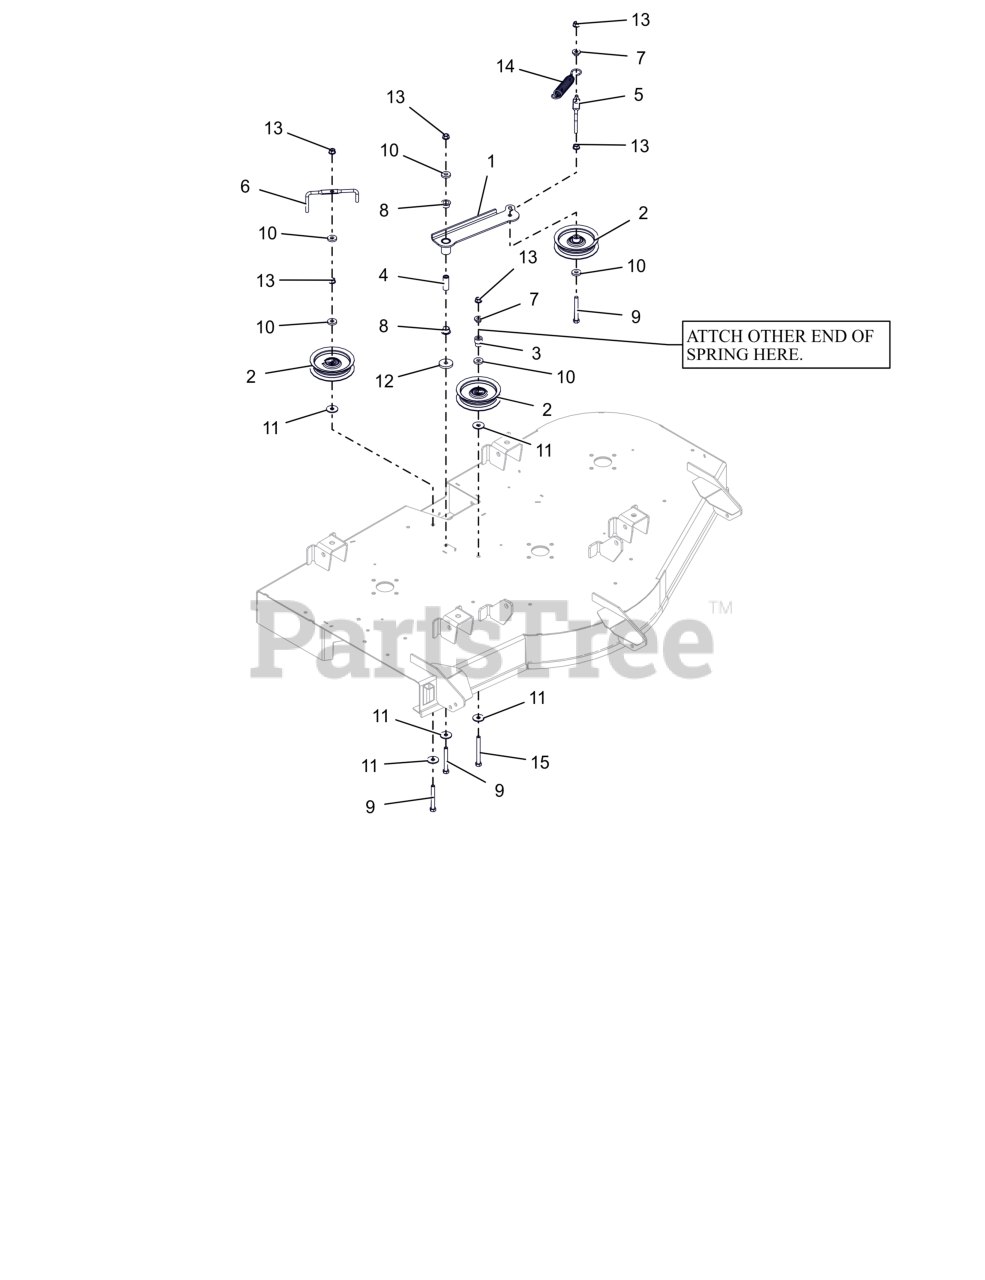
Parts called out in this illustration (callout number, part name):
1	WLDMT, IDLER ARM-52"
2	IDLER, FLAT - 4.06" X .75"
3	BUSHING, IDLER (P/M)
4	SPACER, .375IDX.625ODX1.66 PM
5	WIREFORM, BELT FINGER
6	BELT FINGER
7	BSHG-FLG .385X.500X.875X.406
8	BSHG-FLG, .625X.750X.500X1.00
9	BLT, HEX .38-16X3.00F G5 ZCC
10	WSHR, FLT .406X1.00X.188 ZCC
11	WSHR FL STL .406X1.25X.10ZC120
12	WSHR, FLT .406X1.50X.245 ZCC
13	NUT-LK-CTR-FLG .375-16 GF ZCC
14	SG-TENS .135X.98X6.0 WLD 62
15	BLT, HEX .38-16X3.50 G5 ZCC
